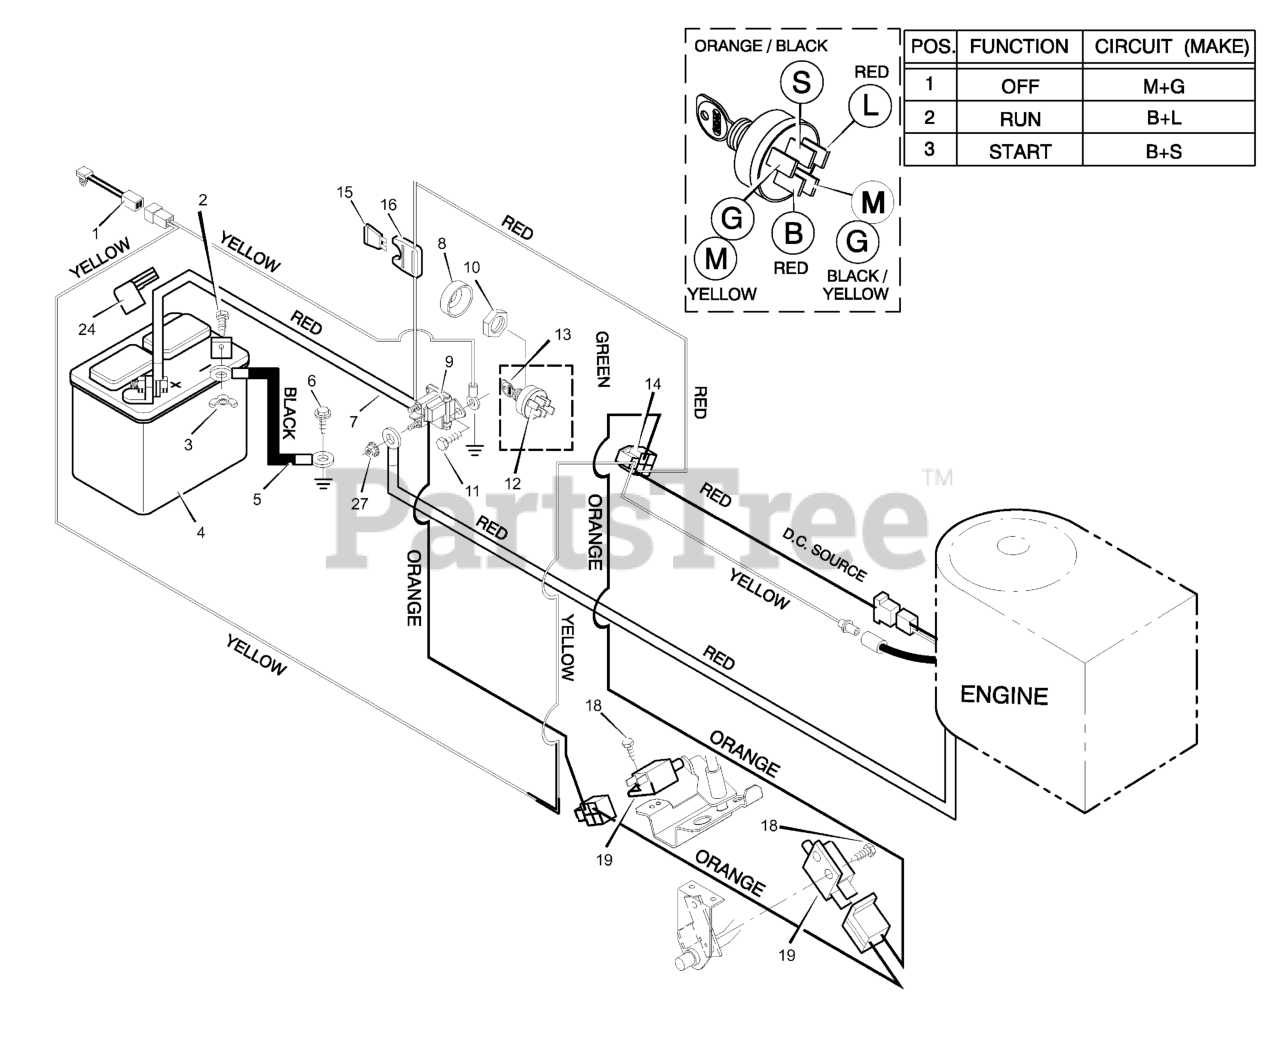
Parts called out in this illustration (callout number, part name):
1	Switch, Seat Sensor
2	Bolt
3	Wingnut
4	Battery
5	Cable, Battery Ground
7	Cable, Red Battery
8	Cap, Ignition
9	Solenoid
10	Nut
12	Switch, Ignition
13	Key, Ignition
14	Harness, Chassis Wire
16	Holder, Fuse
19	Switch, Clutch
24	Cover, Terminal
27	Locknut
